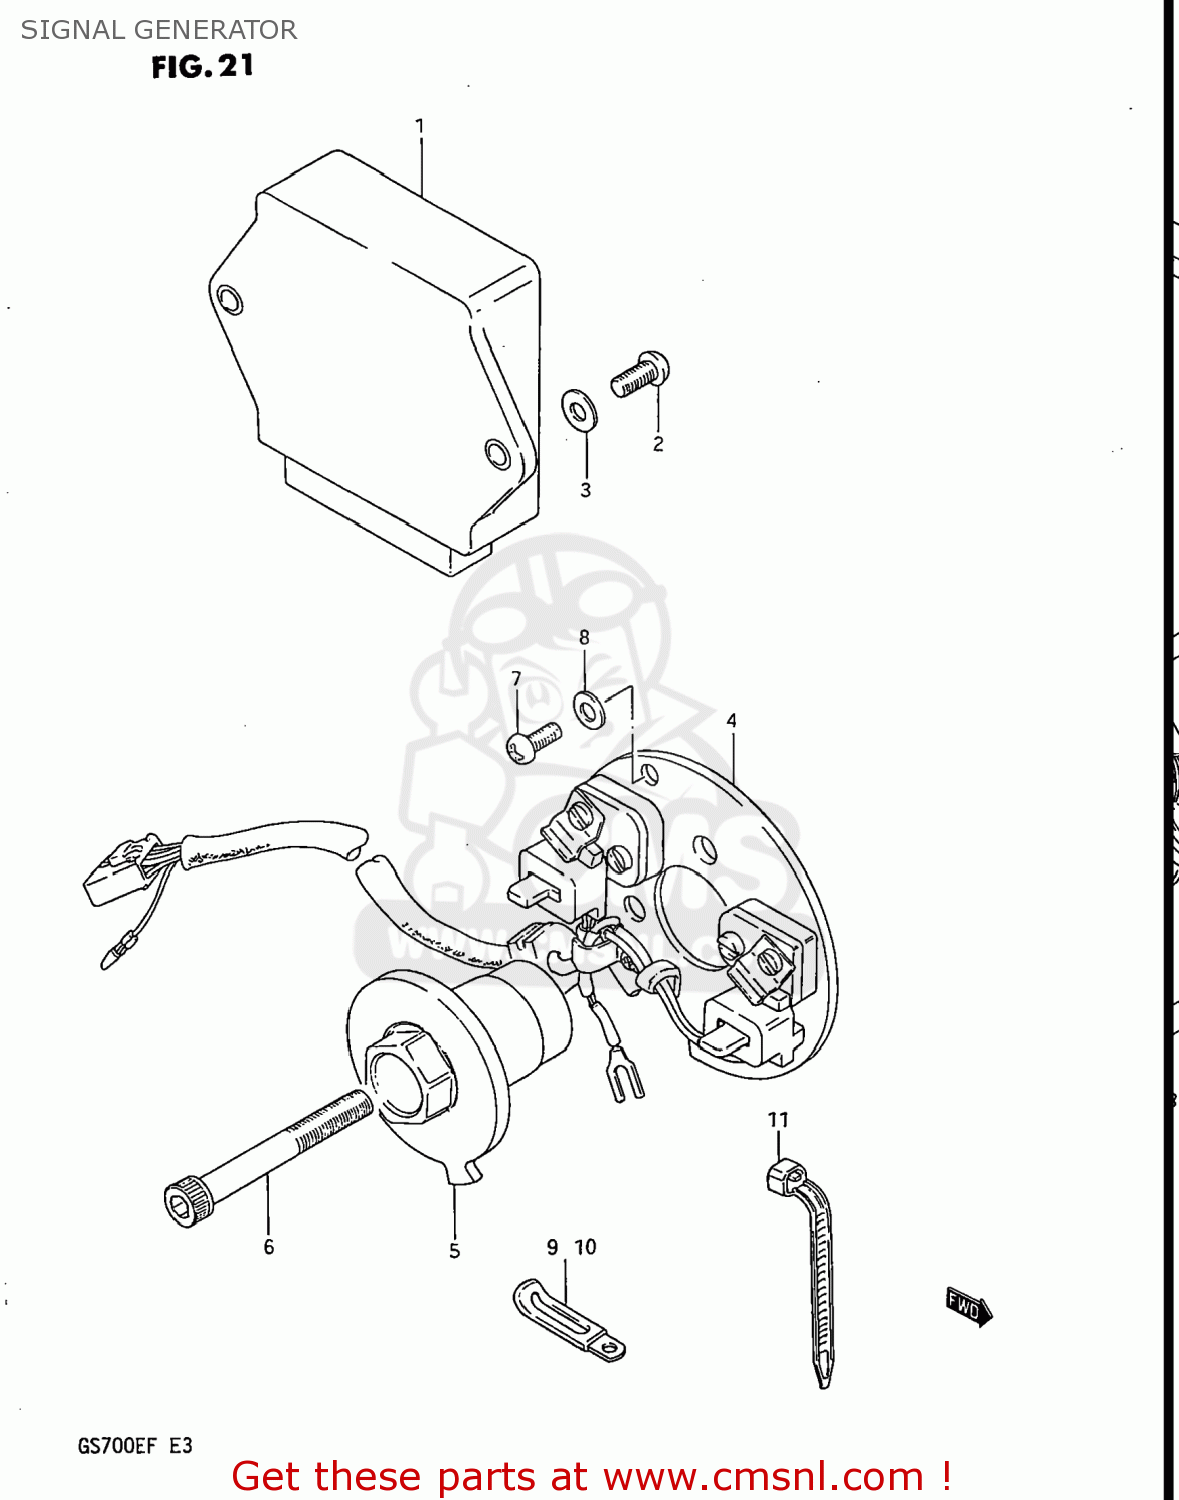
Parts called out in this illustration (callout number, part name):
1	IGNITER UNIT ASSEMBLY
2	SCREW
3	WASHER, LOWER
4	STATOR,SIGNAL GENERATOR
5	ROTOR,SIGNAL
6	BOLT
7	SCREW(5X12)
8	WASHER(5.5X10X0.8)
9	CLAMP
10	CLAMP
11	CLAMP(L:125)
